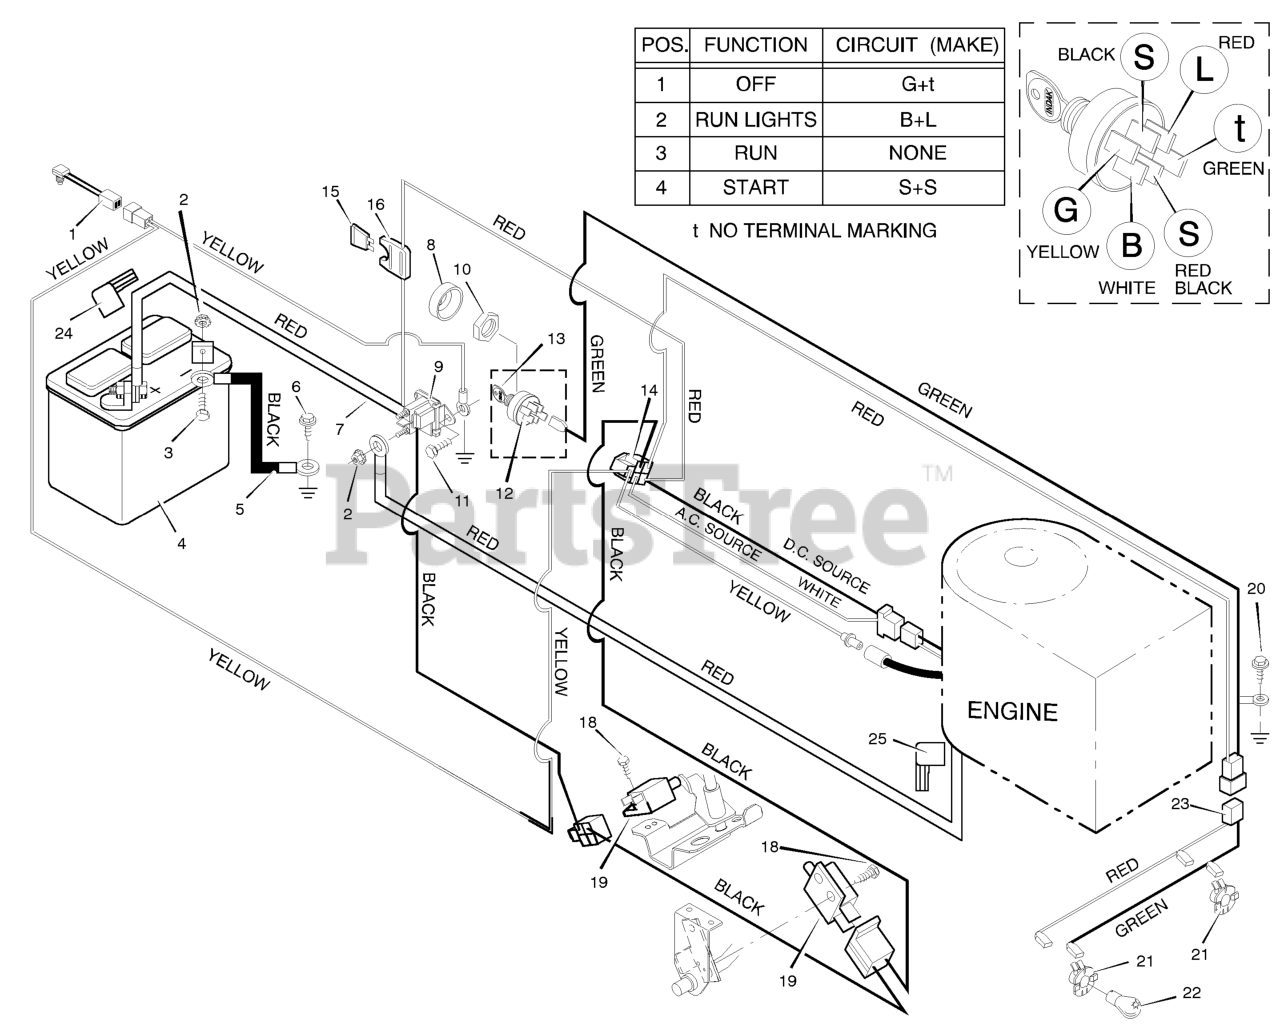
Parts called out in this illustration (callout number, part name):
1	Switch, Seat Sensor
2	Locknut
3	Bolt, Hex
4	Battery
5	Cable, Battery Ground
7	Cable, Red Battery
8	Cap, Ignition
9	Solenoid
10	Nut
12	Switch, Ignition
13	Key, Ignition
14	Harness, Chassis Wire
16	Holder, Fuse
19	Switch, Clutch
20	Screw
21	Socket, Light
22	Bulb, Light
23	Harness, Light Wire
24	Cover, Terminal
